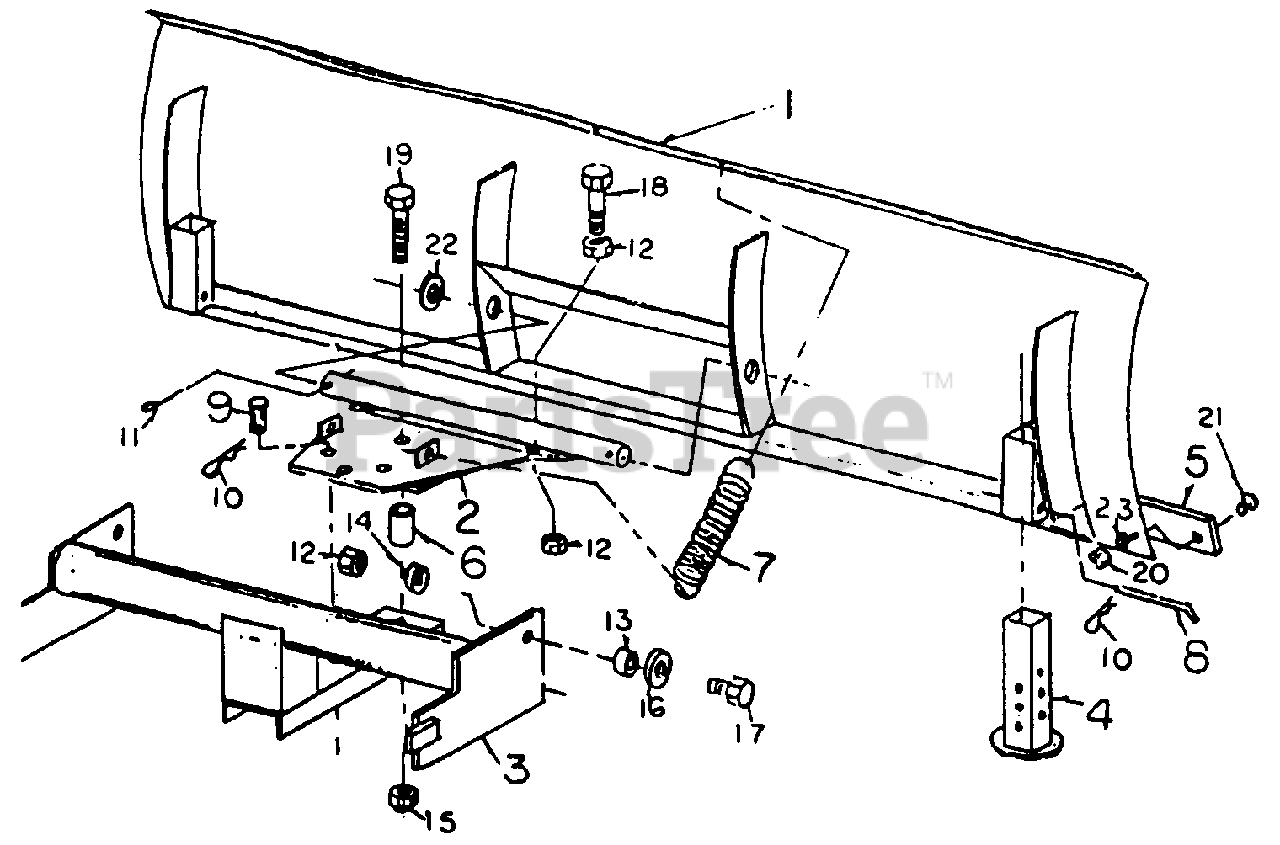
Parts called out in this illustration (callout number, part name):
1	Blade, 54"
2	Pivot Mount
3	Blade Mount, 54"
4	Skid Plate
5	Replaceable Blade
6	Bushing
7	Spring
8	Pin, 3/8"
9	Clevis Pin, 1/2"
10	Hair Pin
11	Cotter Pin, 3/16" x 1"
12	Hex Nut, 1/2-13
13	Bushing
14	Lockwasher, 1/2"
15	Hex Locknut, 1/2"
16	Flatwasher, 1/2"
17	Hex Capscrew, 1/2-13 x 1 1/2", GRS
18	Hex-Capscrew, 1/2-13 x 2 1/4", GRS
19	Hex Capscrew, 1/2-13 x 3", GRS
20	Hex Nut, 5/16-18
21	Carriage Bolt, 5/16-18 x 1"
22	Machine Washer, 3/4"
23	Lockwasher, 5/16"
